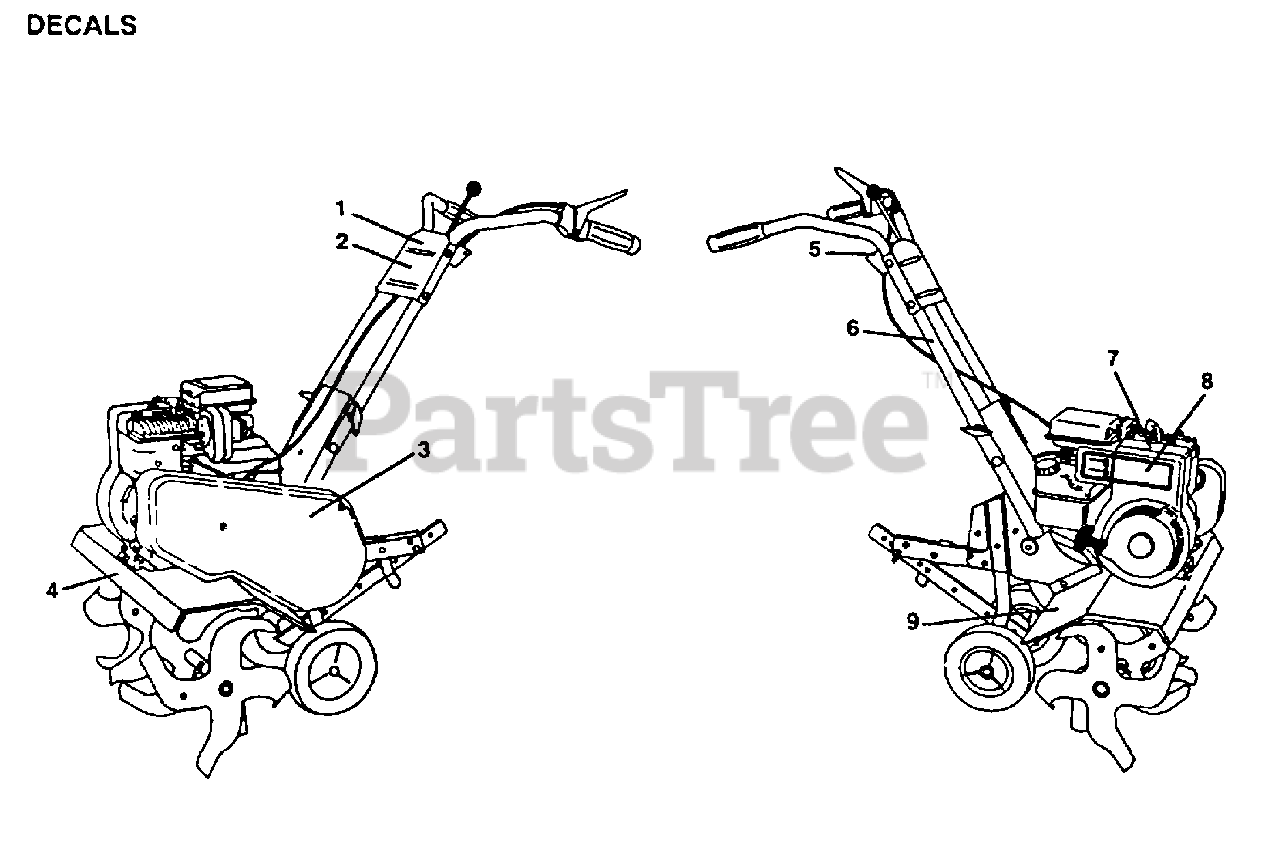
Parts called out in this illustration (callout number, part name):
1	DECAL.PNL.CNT
2	DECAL.PNL.CNT.5HP
3	DECAL.GUARD.BELT
4	DECAL.SHIELD.TINE
5	DECAL REVERSE
6	DECAL TI
9	DECAL TI
